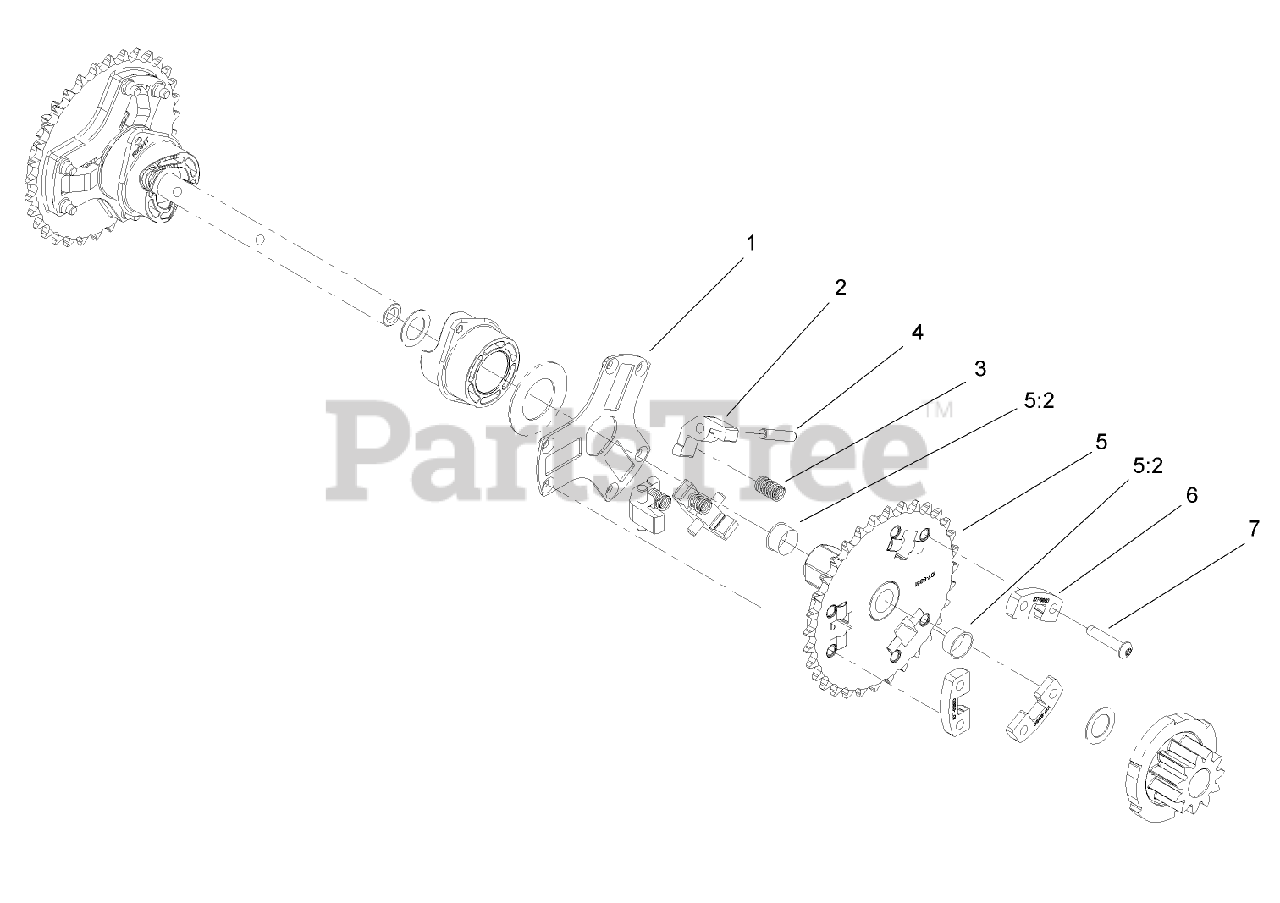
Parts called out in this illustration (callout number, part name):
1	RETAINER-PIN, PAWL
2	PAWL-CLUTCH
3	SPRING-COMPRESSION
4	PIN-DOWEL
5	32T SPROCKET ASM
5:2	BUSHING-FLANGE
6	SUPPORT-PAWL
7	SCREW-TTH, THREAD ROLLING
